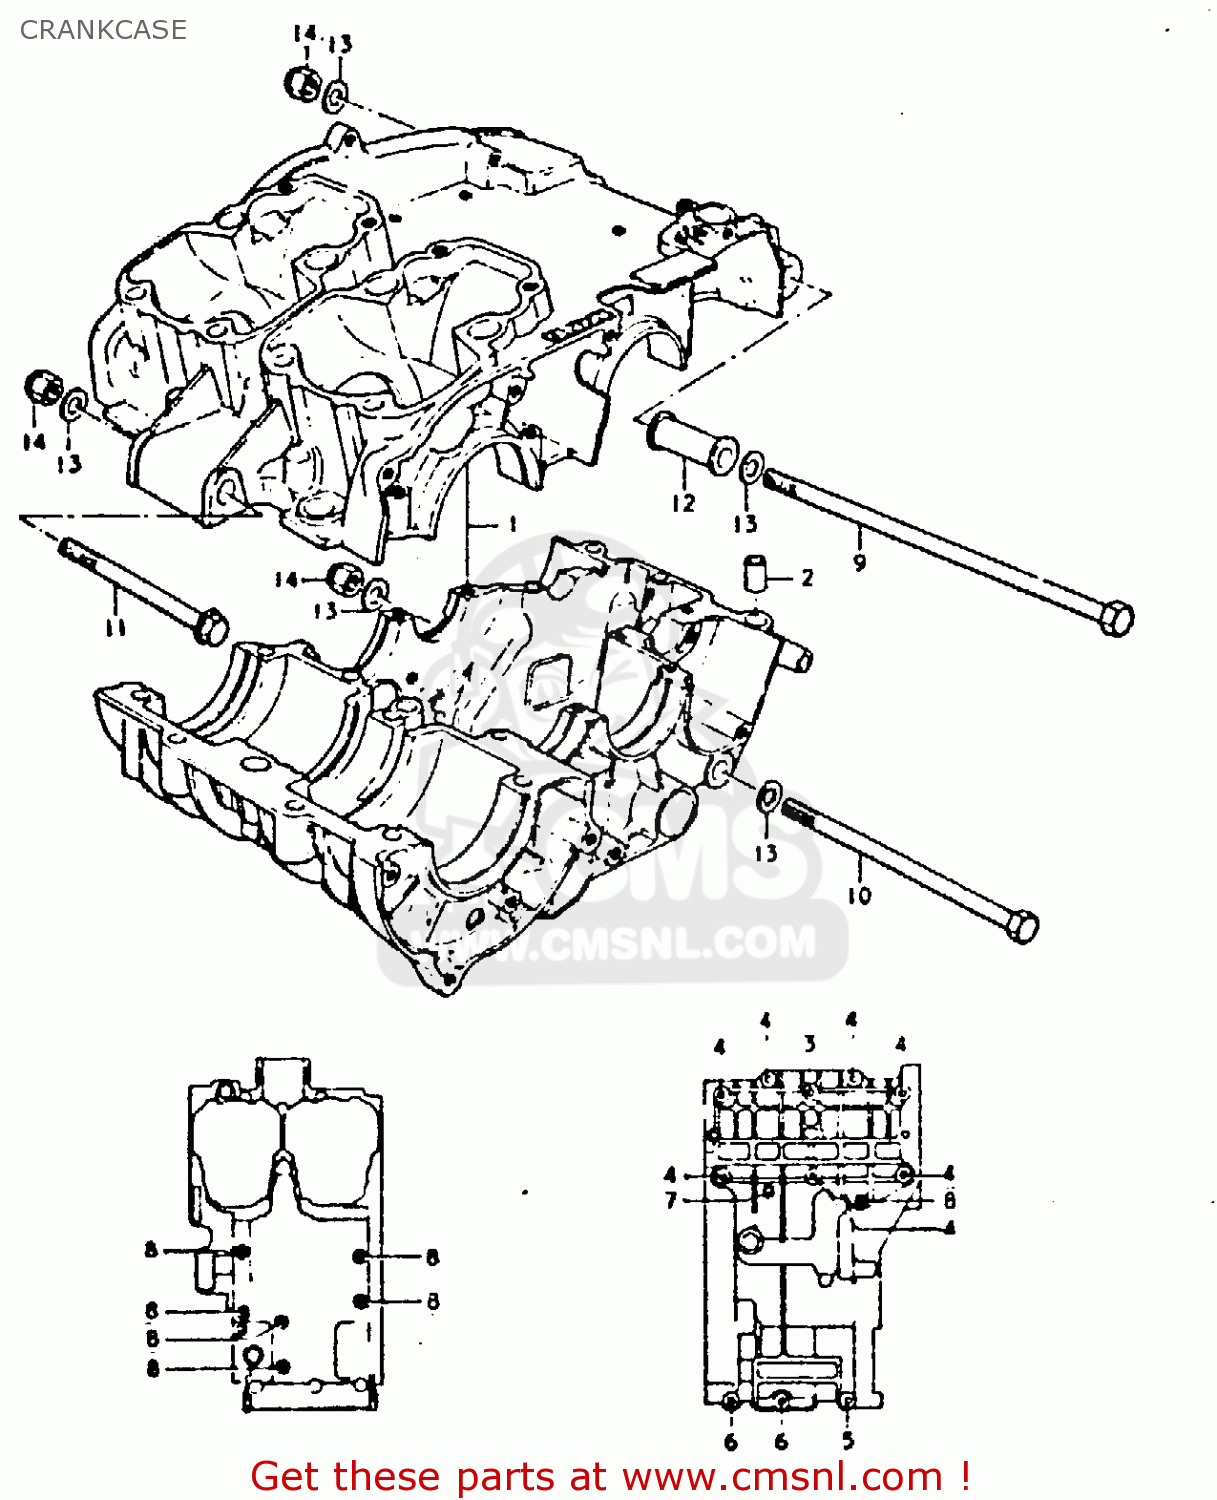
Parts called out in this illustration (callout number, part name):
1	CRANKCASE SET
2	PIN
3	BOLT 8X90
4	BOLT 8X75
5	BOLT 8X55
6	BOLT (8X40)
7	BOLT (6X70)
8	BOLT (6X60)
9	BOLT 10X215
10	BOLT
11	BOLT
12	SPACER,ENGINE MOUNT
13	WASHER
14	NUT
